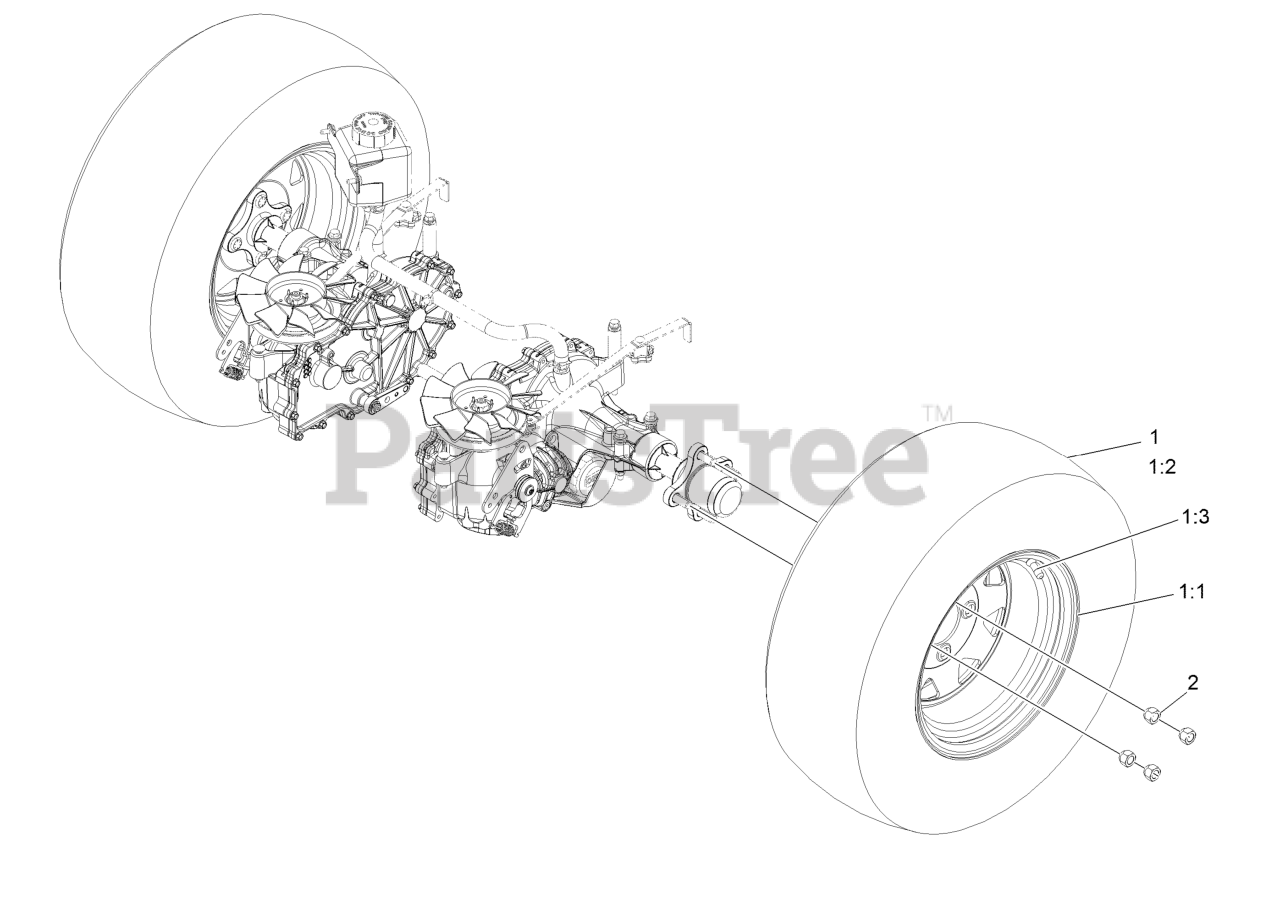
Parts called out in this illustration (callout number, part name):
1	Wheel And Tire ASM
1:2	Tire
1:3	Stem-Valve
2	Nut-Lug
